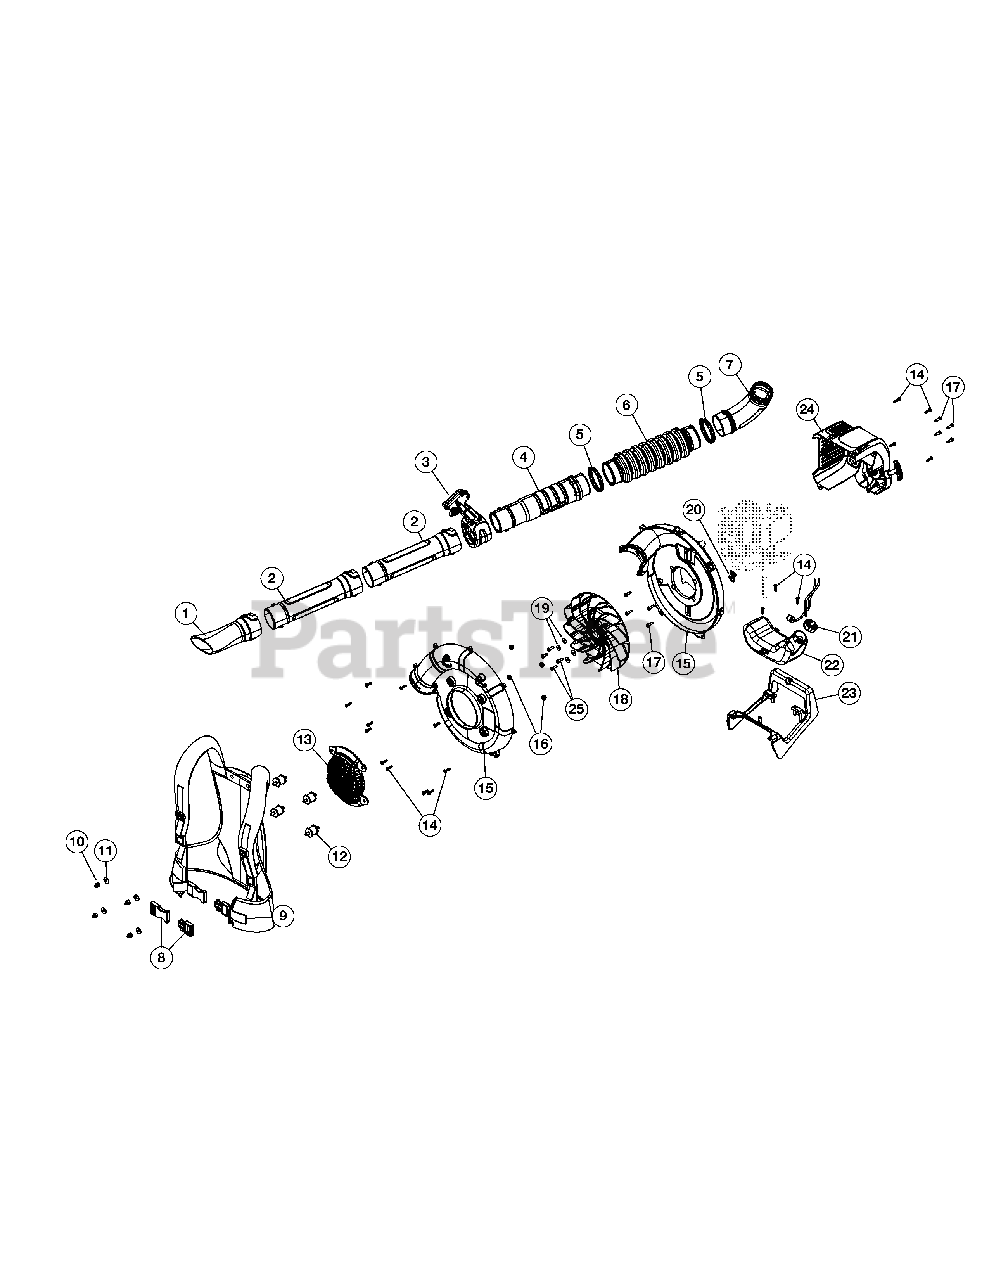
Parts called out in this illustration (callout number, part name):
1	Nozzle
2	Lower Blower Tube
3	Throttle Grip Assembly
4	Upper Blower Tube
6	Flex Tube
7	Elbow Tube
8	Support Clip
9	Support System
10	Nut
11	Spacer
12	Isolator Mount
13	Intake Cover
15	Impeller Housing Assembly
17	Screw
18	Impeller
20	Throttle Retaining Clip
21	Fuel Cap
22	Fuel Tank Assembly
24	Engine Cover Assembly
